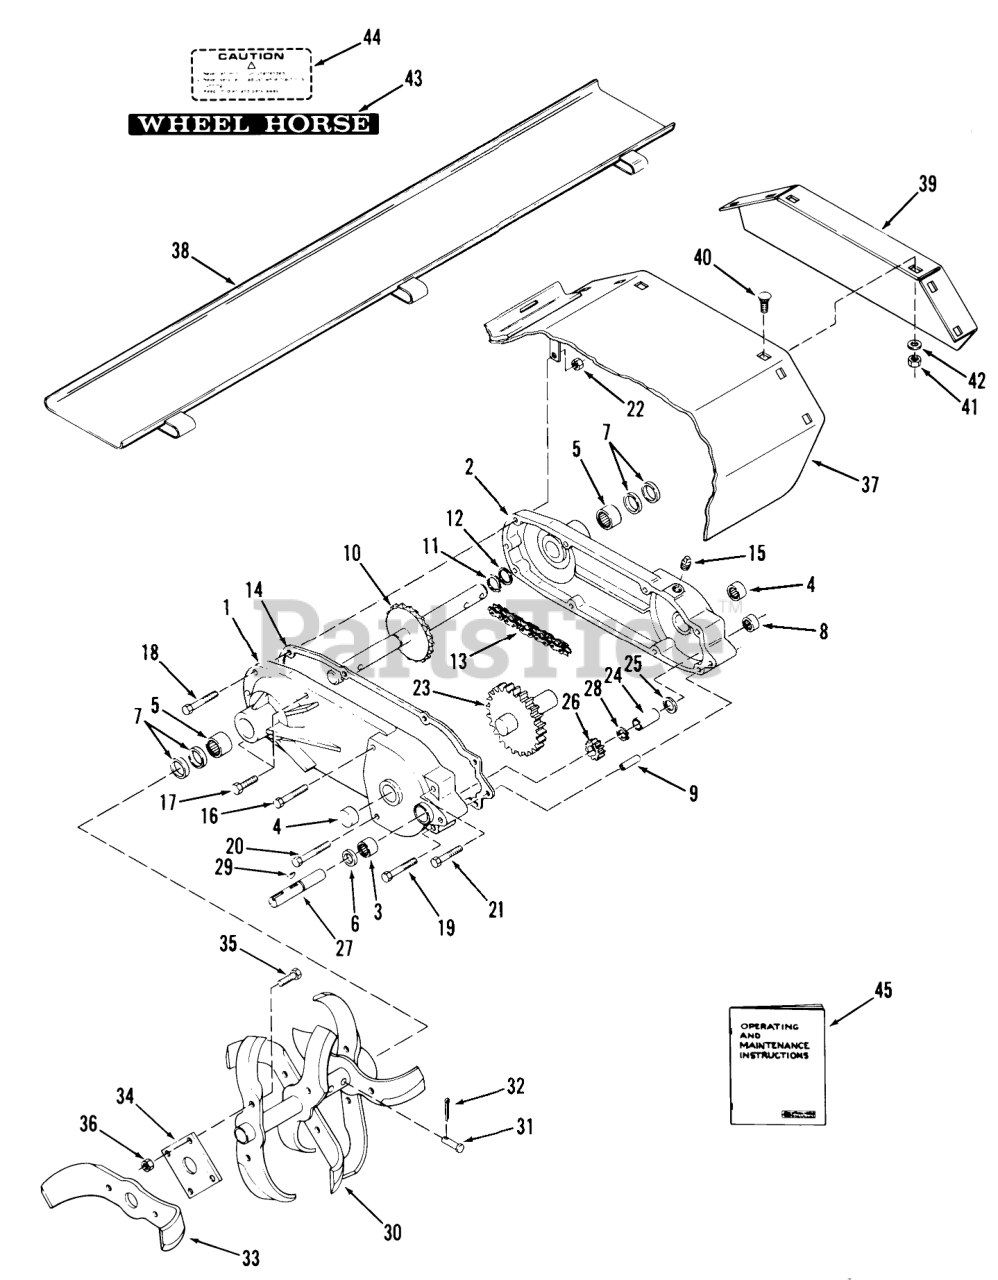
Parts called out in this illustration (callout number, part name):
1	R.H. Case (w/Bearings)
2	L.H. Case (w/Bearings)
3	BEARING-NEEDLE
4	BEARING-NEEDLE
5	BEARING-NEEDLE
6	SEAL-OIL
8	BEARING-NEEDLE
9	ROLL PIN 3/8 X 1
10	TINE SHAFT ASM
11	Snap Ring
12	WASHER
13	CHAIN
14	Gasket
15	SOLID PIPE PLUG
16	H H C S
17	Bolt
18	HHCS
19	BOLT
20	Hex Bolt
21	Bolt 3/8-16 x 4
22	NUT
23	GEAR AND SHAFT ASM
24	Spacer
25	WASHER-THRUST
26	GEAR-PINION
27	SHAFT-INPUT
28	RING-SNAP, EXTERNAL
29	Key
30	Tine R.H.
30	Tine L.H.
31	PIN-CLEVIS
33	R.H. Tine
33	L.H. Tine
34	Plate-Tine Mounting
35	H H C S
36	Nut
37	X-REF 92-6514-01
38	Rear Shield
39	Cover-End
40	CARRIAGE BOLT -4
41	Nut
42	WASHER 5/16 SAE
43	DECAL-WHEEL HORSE
44	Caution Decal
45	Operating and Maintenance Instructions
